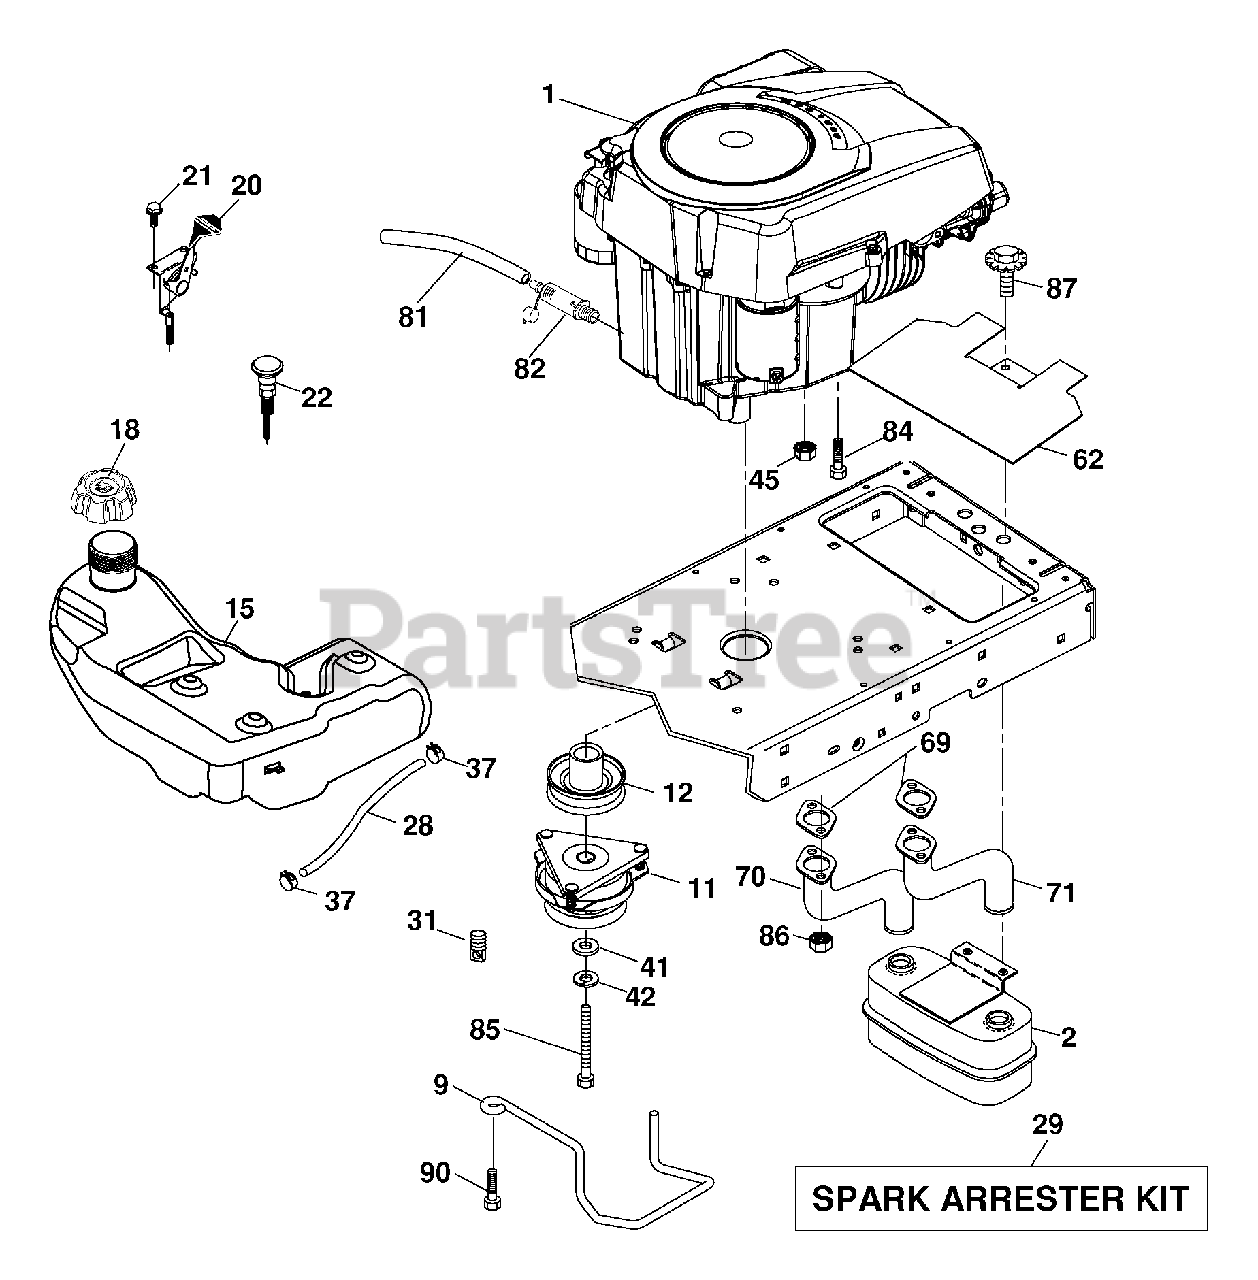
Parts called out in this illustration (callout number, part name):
2	Muffler
9	Keeper Asm. Belt Engine
11	Clutch Electric
12	Pulley Engine
15	Tank Fuel 4.0
18	Cap Asm
20	Control Throttle
21	Screw 10 x 3/4 Single Lead-Hex
22	Control Choke
28	Fuel Line
29	Spark Arrester Kit
31	Clip Push-In Hinged
37	Clamp Hose
41	Washer 1-1/2 OD x 15/32 ID x .250
42	Washer Lock 7/16
45	Nut Keps Hex 1/4-20 unc
62	Shield Heat Muffler
70	Tube Exhaust LH
71	Tube Exhaust RH
80	Nut Flange M8-1.25
81	Tube Drain Oil Easy
82	Plug Drain Oil
84	Screw 3/8-16 x 1-1/2
85	Bolt Hex 7/16-20 x 3.75 Gr. 5
86	Nut Flange Toplock M8-1.25
87	Bolt 5/16-18 unc x 1 w/Sems
90	Screw 3/8-16 x 1
91	Bushing
